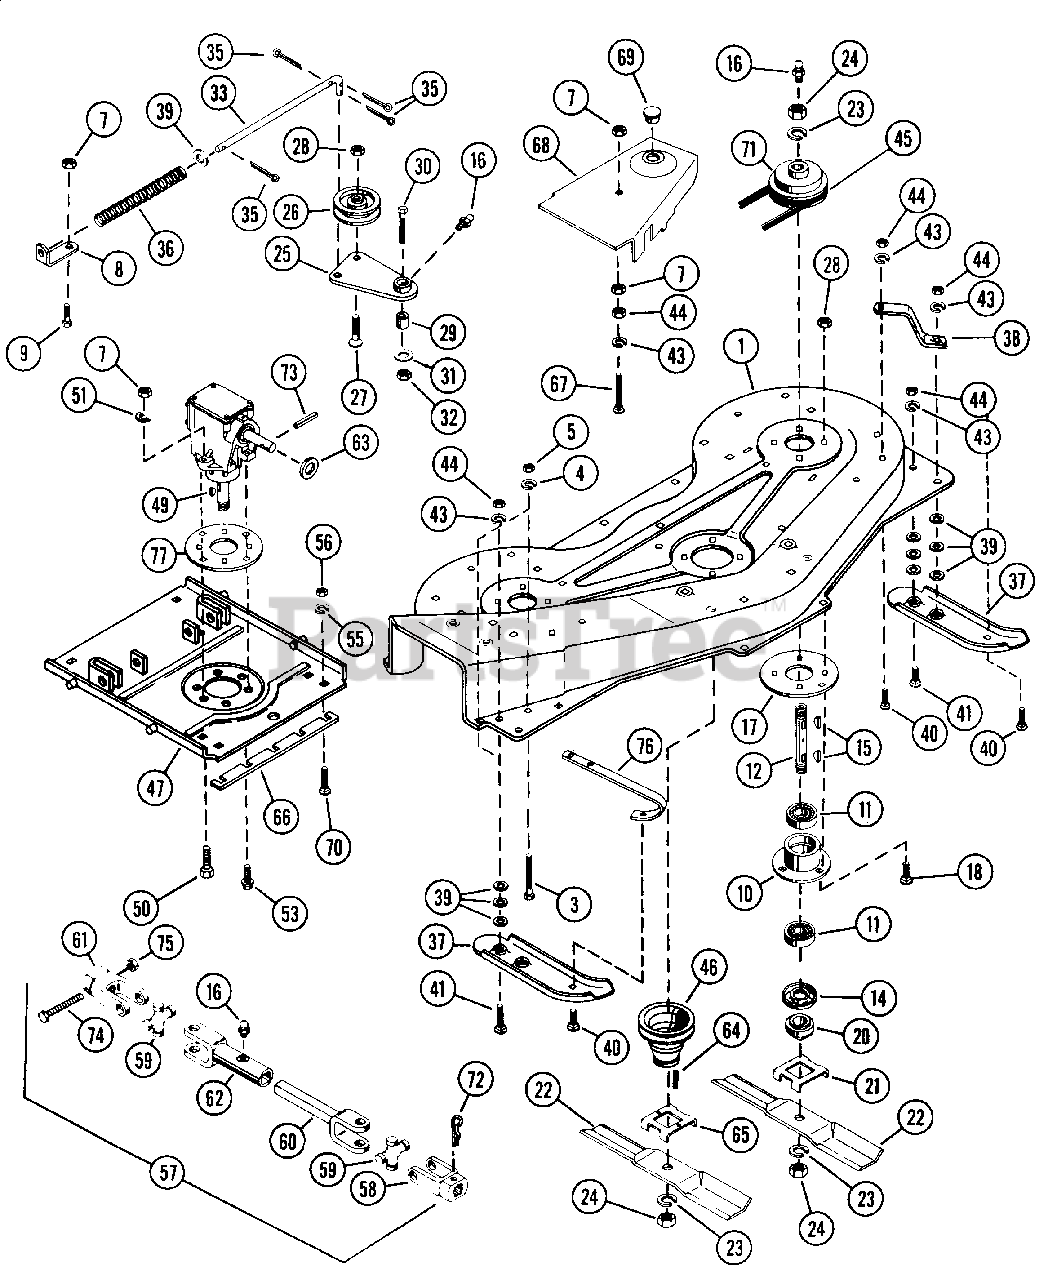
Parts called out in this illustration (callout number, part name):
1	48-INCH DECK
3	BOLT, HEX 3/8-16X2.50
4	WASHER, LOCK 3/8 REG.
5	NUT, HEX 3/8-16
7	NUT, LOCK 5/16-18
8	BRACKET
9	BOLT, HEX 5/16-18X.50
10	SPINDLE HOUSING
11	RADIAL BEARING
12	SPINDLE SHAFT
14	BEARING SLINGER
15	KEY, WOODRUFF .187X.625 HARD #61
16	FITTING, LUBE 1/4-28
17	SPACER, SPINDLE
18	BOLT, CARRIAGE 3/8-16X.75
20	RETAINER HUB
21	BLADE TRAY
22	BLADE
23	WASHER, LOCK 3/4 SP
24	NUT, JAM 3/4-10 HEX
25	IDLER ARM
26	IDLER
27	SCREW, CAP 3/8-16X1.25 BTHD
28	NUT, LOCK 3/8-16
29	SPACER, PIVOT
30	BOLT, CARRIAGE 1/2-13X2.50
31	WASHER, FLAT .56X1.87X.109
32	NUT, LOCK 1/2-13
33	ROD, IDLER SPRING
35	PIN, COTTER .09X.75
36	SPRING
37	SKID
38	SKID BRACE, L.H.
39	WASHER, FLAT .406X.812X.065
40	BOLT, CARRIAGE 5/16-18X.75
41	BOLT, CARRIAGE 5/16-18X1.00
43	WASHER, LOCK 3/8 SP HEAVY
44	NUT, HEX 5/16-18
45	V-BELT
46	SHEAVE
47	MOUNTING PLATE
49	KEY, WOODRUFF .25X.75X.312
50	BOLT, HEX 5/16-18X1.25
51	SHIM
53	TAPTITE, 5/16-18X1.00 THHPL
55	WASHER, LOCK 1/2 SP HEAVY
56	NUT, HEX 1/2-13
57	ASSEMBLY, PTO(CONSISTS OF ITEM NUMBERS 16,58, 59, 60, 61, AND 62)
58	YOKE
59	JOURNAL CROSS AND BEARING ASSEMBLY
60	YOKE AND SHAFT
61	YOKE
62	SLIP YOKE
63	WASHER, .749/.759X1.000X.032
64	PIN, GROOVE .187X.75 TYPE A
65	TRAY
66	SHIM
67	BOLT, CARRIAGE 5/16-18X3.25
68	COVER, R.H. BELT
68	COVER, L.H. BELT
69	BUTTON PLUG
70	BOLT, 1/2-13X1.50 RD HD SQ NK
71	SHEAVE
72	PIN, HAIR INT. .187X3.25
73	PIN, SPRING .125X1.000
74	SCREW, CAP 1/4-20X2.125 GR 5 HH
75	NUT, LOCK 1/4-20
76	SKID BRACE, R.H.
77	SHIM
